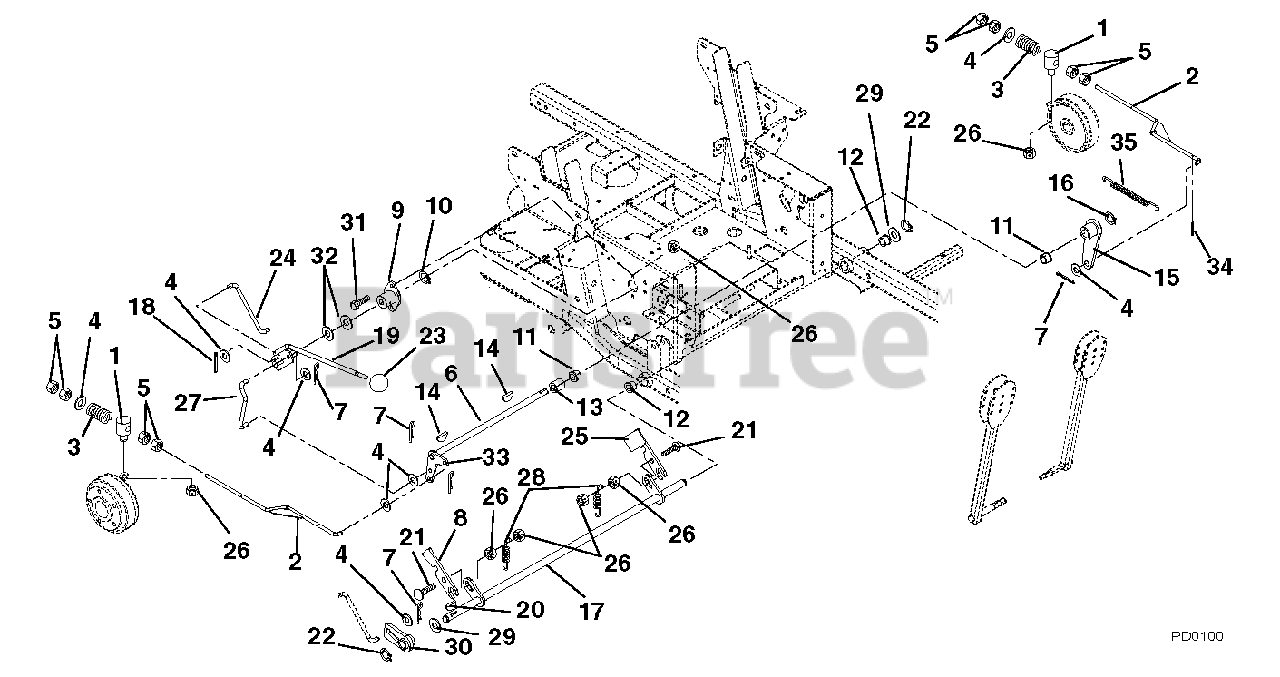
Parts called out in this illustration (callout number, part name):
1	Pivot, Brake Rod
2	Rod, Brake 200 XDZ LPG
3	Spring, Compression .142 x .710 x 1.75
4	Washer, Flat Steel .406 x .812 x .065
5	Nut, Hex .38-16
6	Shaft, Brake Cross
7	Pin, Hair
8	Slide, Interlocking Brake
9	Bushing, Flange
10	Ring, Retaining External .625 x .05
11	Bushing, Flange Nylon .762 x 1.00 x .58 x 1.48
12	Bushing, Flange .515 x .75 x .745 x 1.00
13	Bushing, Sleeve .75 x 1.00 x .75
14	Key, Woodruff .19 x .75 Hard #9
15	Weldment, Brake Arm
16	Ring, Retaining External .689 x .078
17	Weldment, Mechanical Brake
18	Pin, Cotter External .09 x .75
19	Weldment, Brake Actuating
20	Key, Woodruff .13 x .63
21	Bolt, Round Head Square Neck .31-18 x 1.25 Grade 5
22	Ring, Retaining External .50 x .05
23	Grip, Handle
24	Linkage, Brake Actuating
25	Interlock, Safety Switch
26	Nut, Locking Top Flange .31-18
27	Linkage, Brake Actuating
28	Spring, Tension .063 x .44 x 1.56
29	Washer, Flat Steel .505 x 1.00 x .062
30	Weldment, Parking Brake Hub
31	Bolt, Hex .31-18 x .75 Grade 5
32	Washer, Flat Steel .630 x 1.250 x .062
33	Weldment, 200 Brake Actuating Arm
34	Pin, Cotter 12 x .75 Extended Prong Square Cut
35	Spring, Extension
